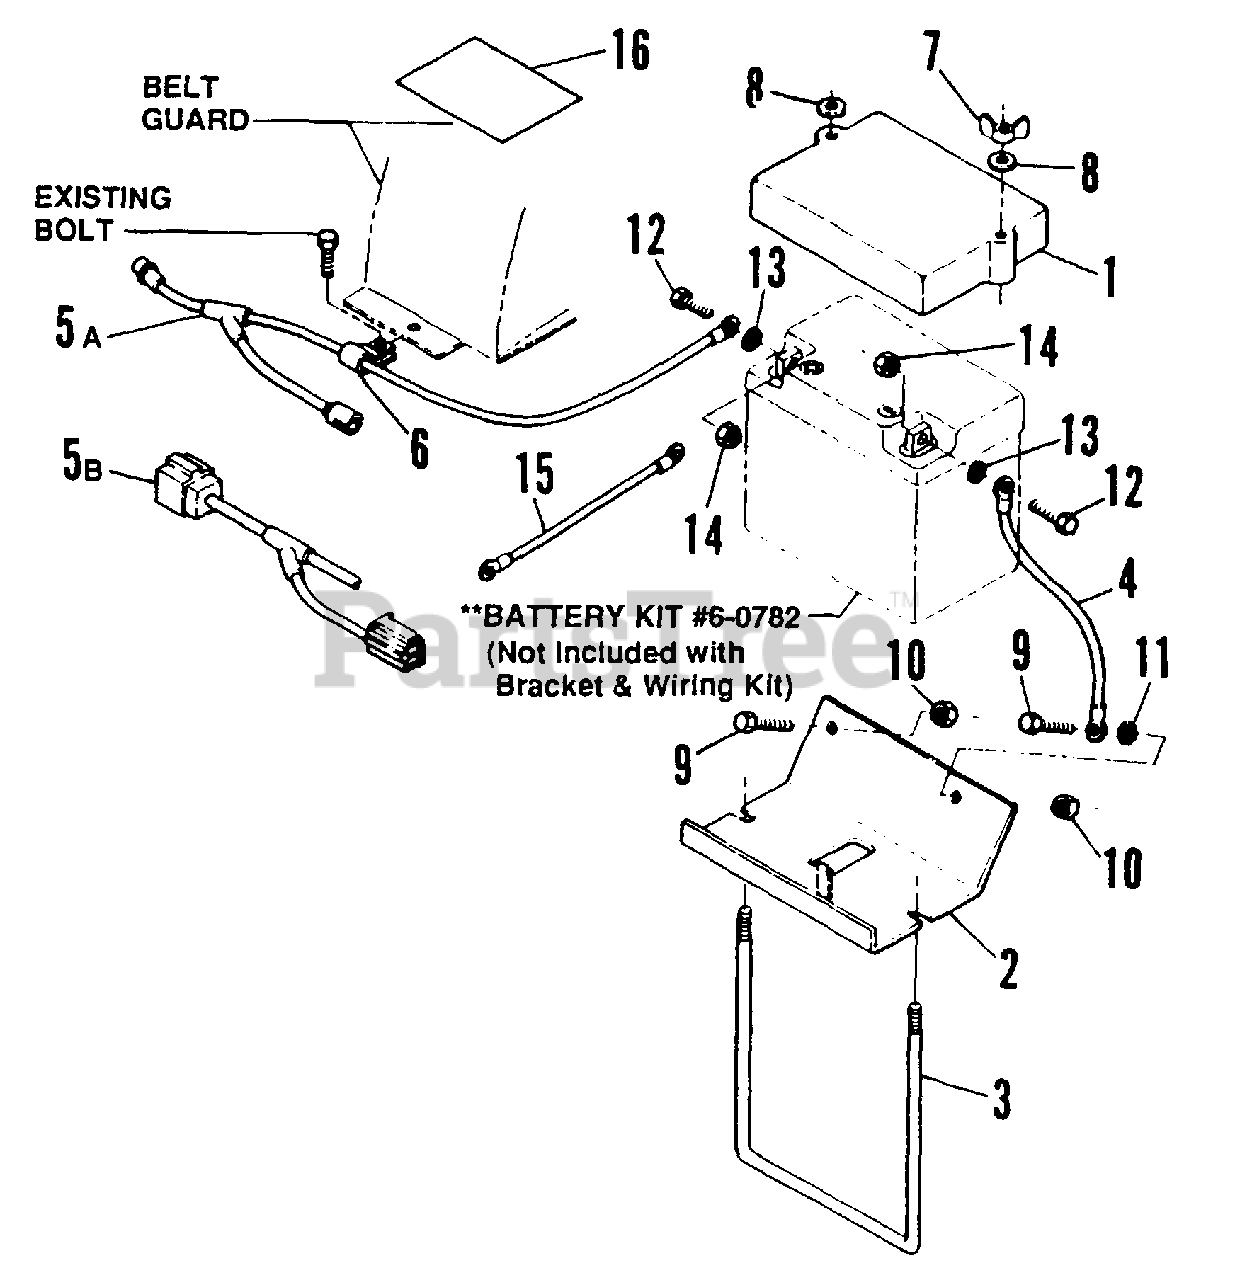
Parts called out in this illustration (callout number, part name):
1	COVER, Battery
2	BRACKET, Mounting
3	CLAMP, Battery
4	WIRE, Ground
5A	WIRE, Charging
5B	WIRE, Charging
6	CLIP, Harness
7	NUT, 1/4-20 Wing
8	WASHER, 1/4 Flat
9	SCREW, 5/16-18 x 5/8" Hex Cap
10	NUT, 5/16-18 Hex Center Lock
11	WASHER, 5/16 Internal External Tooth
12	SCREW, #10-24 x 1/2" Hex Cap
13	WASHER, #10 External Tooth Lock
14	NUT, #10-24 Hex Whiz lock
15	WIRE, Battery to Switch
16	DECAL, Charging Instructions
60782	KIT, Battery
